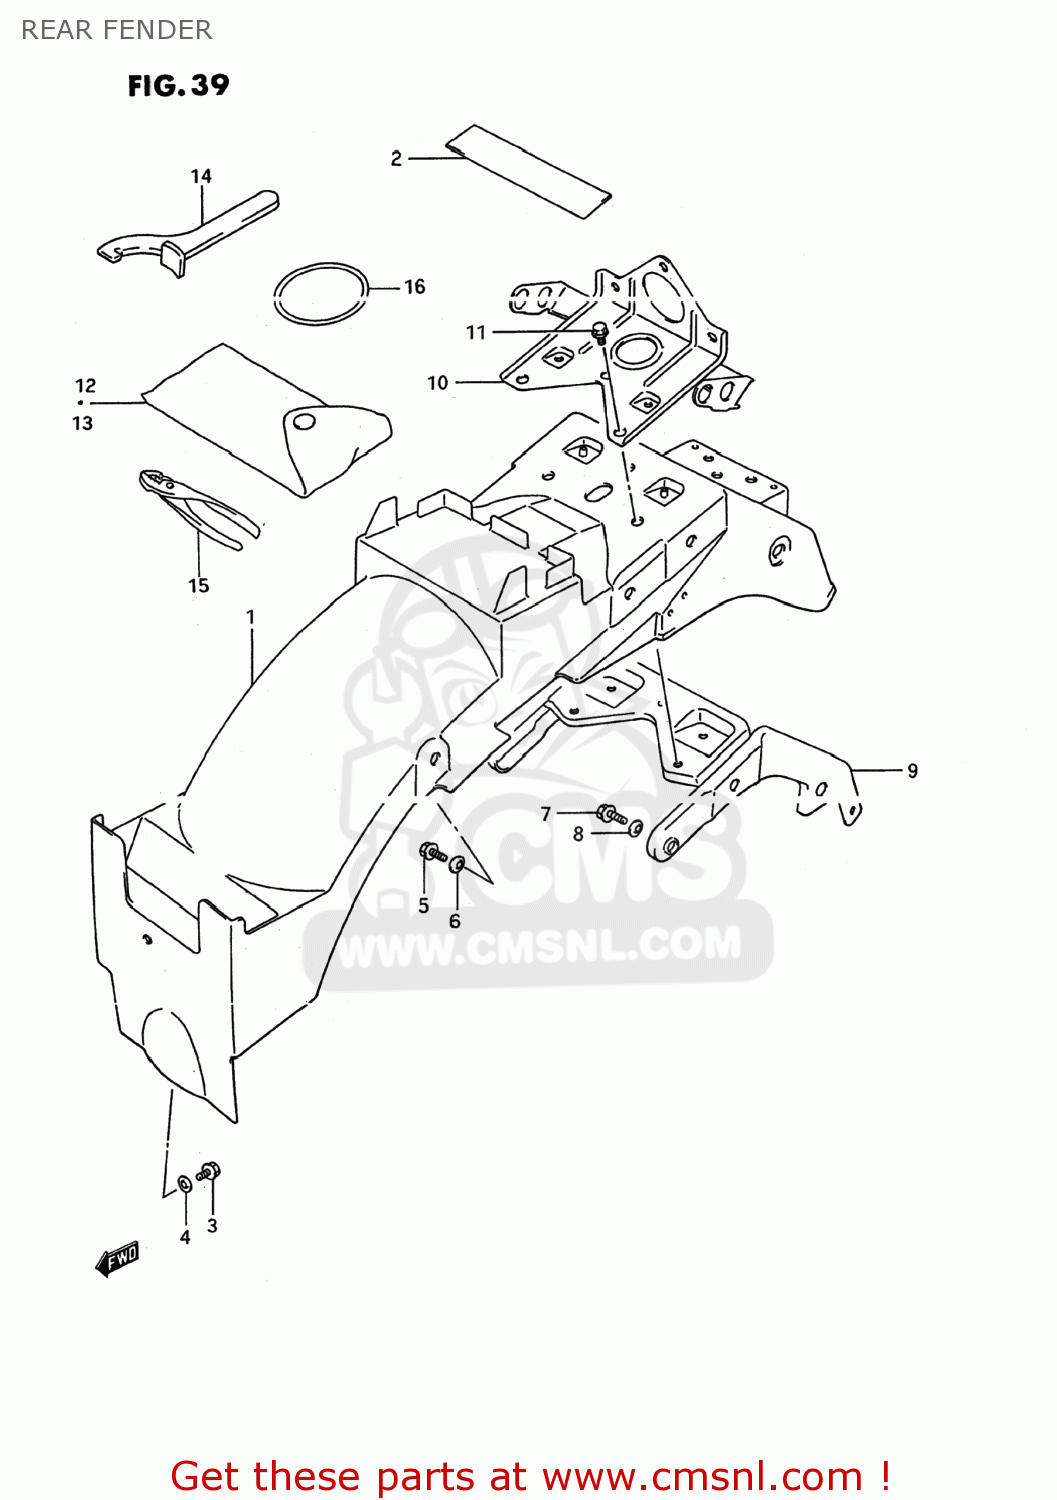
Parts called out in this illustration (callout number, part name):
1	BODY,REAR FENDER
2	CUSHION,RR FENDER
3	BOLT
4	WASHER
5	BOLT
6	WASHER
7	BOLT
8	WASHER
9	REINF,RR FENDER
10	BRACKET,RR LAMP
11	BOLT
12	TOOL ASSY
13	TOOL ASSY
14	CLAMP
15	SPANNER,HEXAGON
16	O RING(D:3.5,ID:61)
17	MANUAL,OWNER'S
